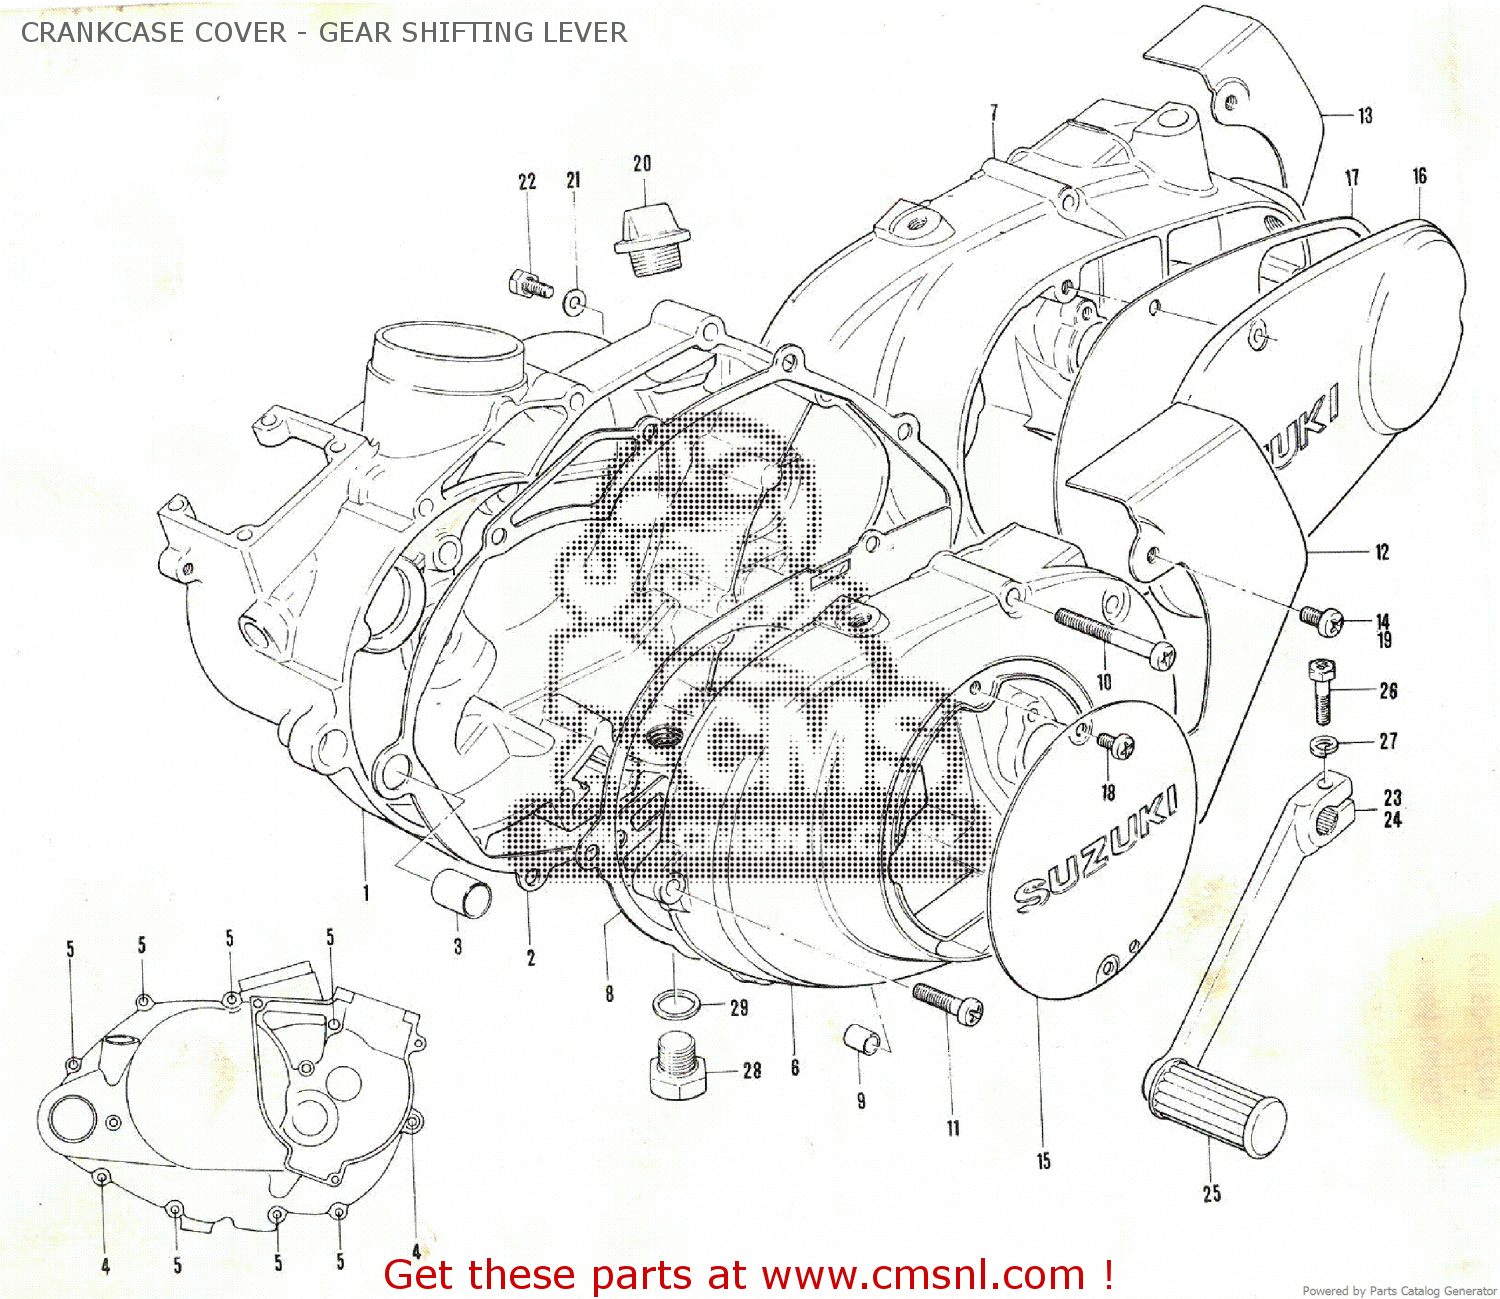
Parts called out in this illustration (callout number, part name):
1	ART3
2	ART6
3	ART8
4	ART9
5	ART10
6	ART11
7	ART12
8	ART13
9	ART14
10	ART15
11	ART16
12	ART17
13	ART18
14	ART19
15	ART20
16	ART21
17	ART22
18	ART23
19	ART24
20	ART25
21	ART26
22	ART27
23	ART28
24	ART29
25	MUFFLER
